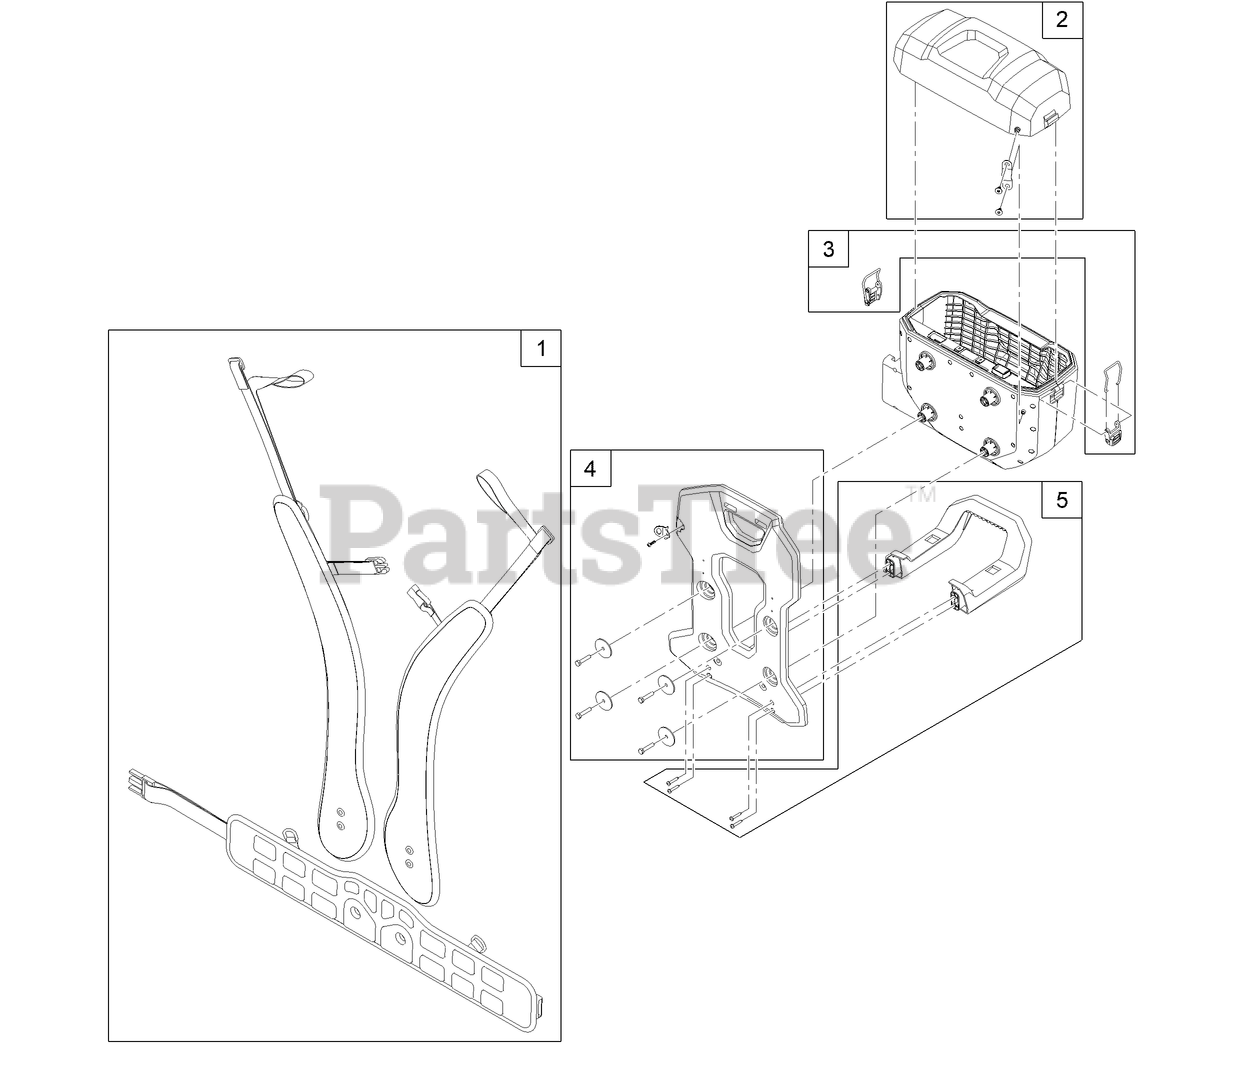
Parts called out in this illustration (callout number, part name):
1	HARNESS-SHOULDER/HIP STRAPS KIT
2	COVER-BATTERY HOUSING
3	LATCH-BATTERY HOUSING
4	PLATE-BATTERY HOUSING MOUNT
5	BRACE-BACKPACK PLATE
